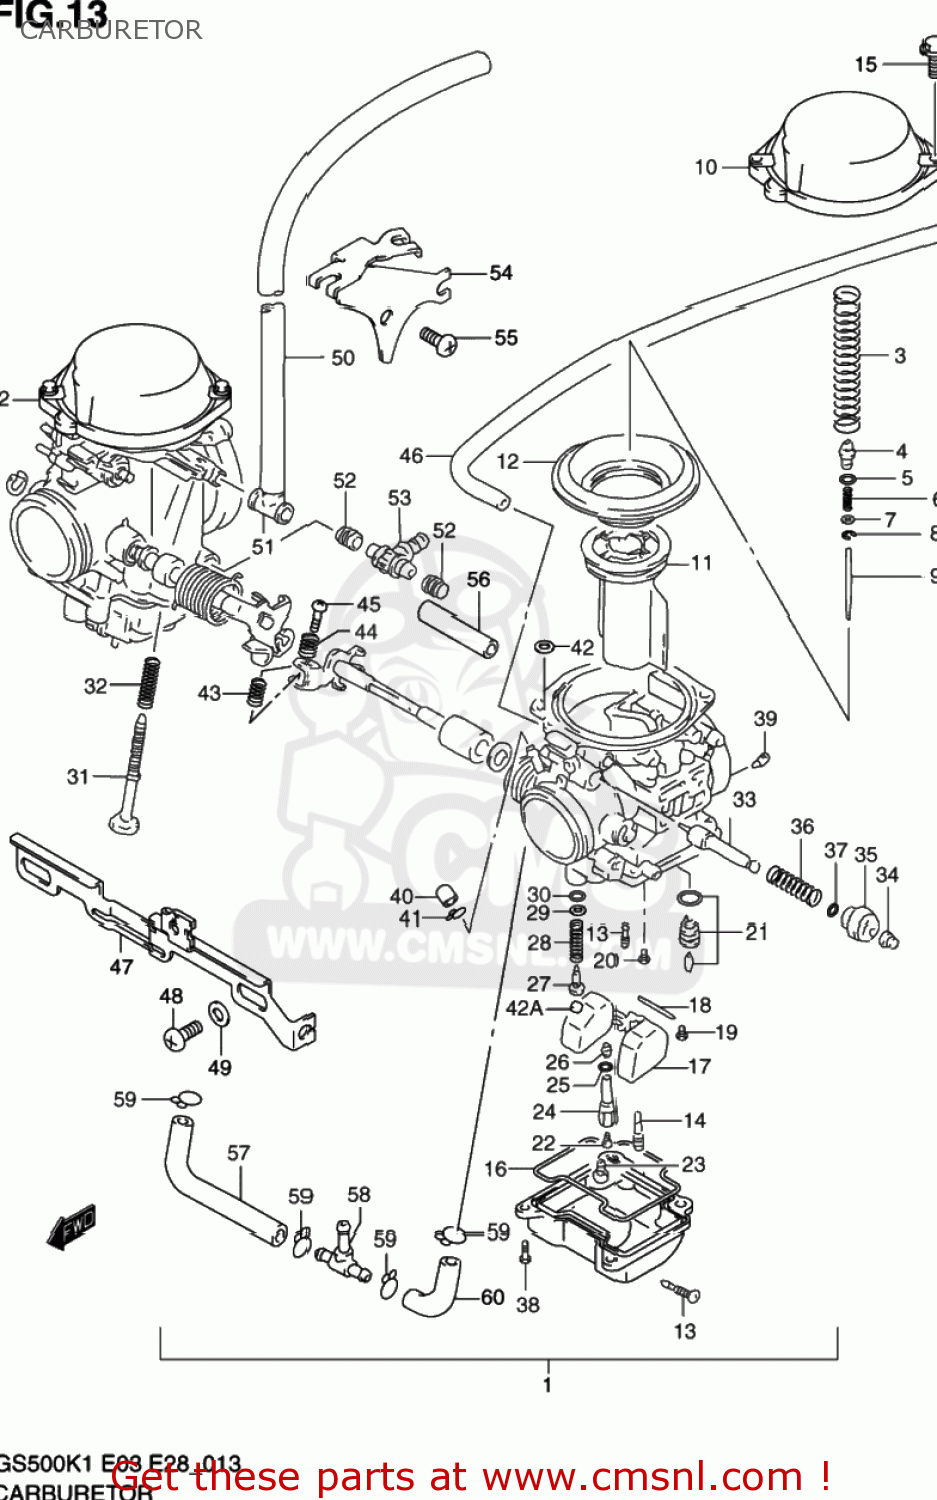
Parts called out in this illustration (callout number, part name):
1	CARBURETOR ASSY,L
2	CARBURETOR ASSY,R
3	SPRING
4	HOLDER
5	O RING(D:1.9,ID:4.8)
6	SPRING
7	WASHER
8	RING
9	NEEDLE,JET(5DH42-1)
10	COVER ASSY,DIAPHRAGM
11	VALVE,PISTON
12	DIAPHRAGM
13	PLUG,DRAIN
14	JET,PILOT(17.5)
15	SCREW
16	GASKET (NAS)
17	FLOAT ASSY
18	PIN,FLOAT
19	SCREW
20	SCREW
21	VALVE ASSY,NEEDLE(NI)
22	JET,MAIN(127.5)
23	JET,MAIN(60)
24	HOLDER,JET
25	O RING
26	JET,NEEDLE(P-5M)
27	ADJUSTER
28	SPRING
29	WASHER
30	O RING,PILOT AIR SCREW
31	SCREW,ADJUST
32	SPRING
33	PLUNGER
34	CAP,STARTER VALVE
35	GUIDE SCREW,PLUNGER
36	SPRING
37	O RING
38	SCREW
39	JET,AIR(160)
40	CAP
41	CLIP
42	O RING
42A	PLUG
43	SPRING,THROTTLE SCREW
44	SPRING
45	SCREW
46	HOSE
47	PLATE
48	SCREW
49	PACKING
50	HOSE
51	HOSE
52	SEAL
53	NIPPLE
54	BRACKET
55	SCREW
56	PIPE
57	HOSE
58	NIPPLE
59	CLIP
60	HOSE
